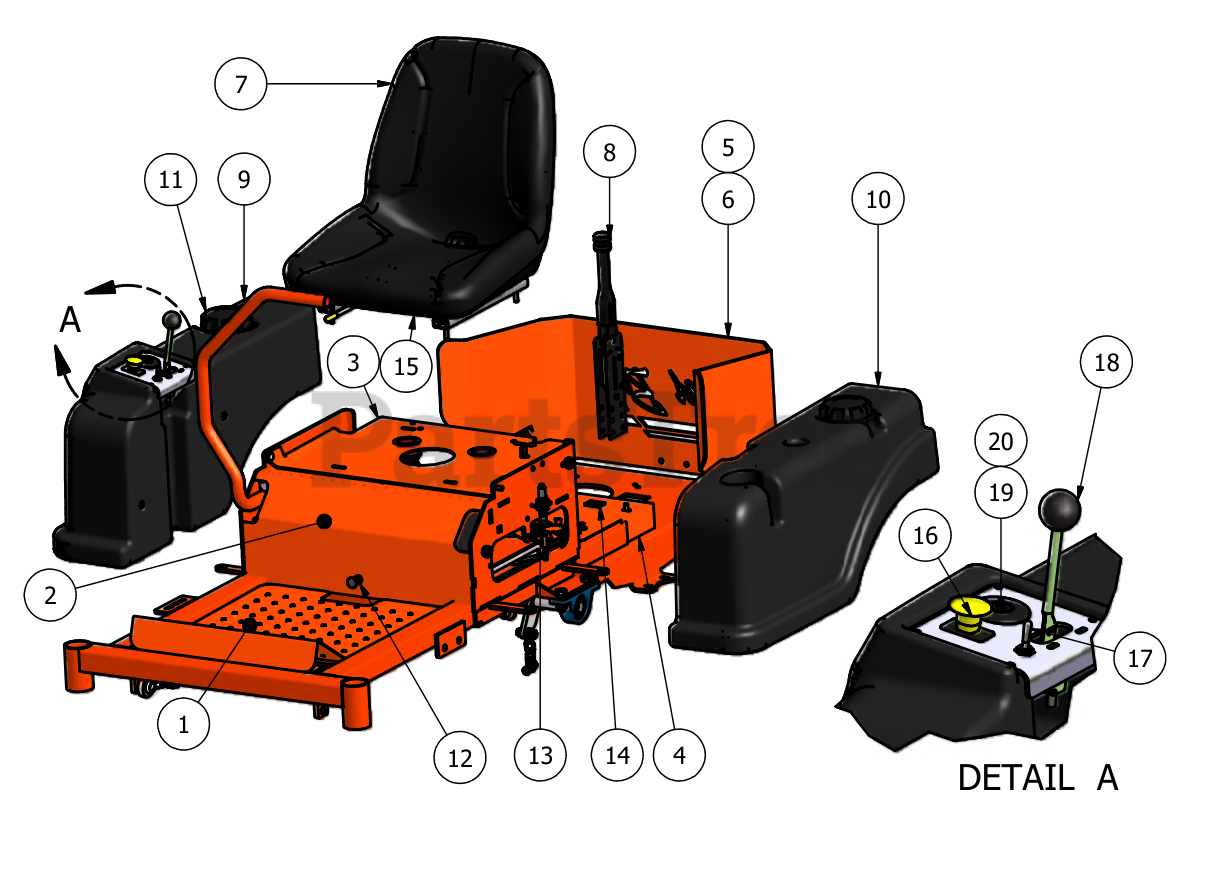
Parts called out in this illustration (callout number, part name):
1	ZT Floor Panel
2	Cooler Cover
3	Seat Mounting Plate
5	ZT Rear Plate 26HP
6	ZT Rear Plate 23HP
7	Seat Assembly
8	Hand Brake
9	Right Tank
13	Brake Cable
14	Tachometer
15	Seat Safety Switch
16	PTO Engager
19	Ignition Switch
